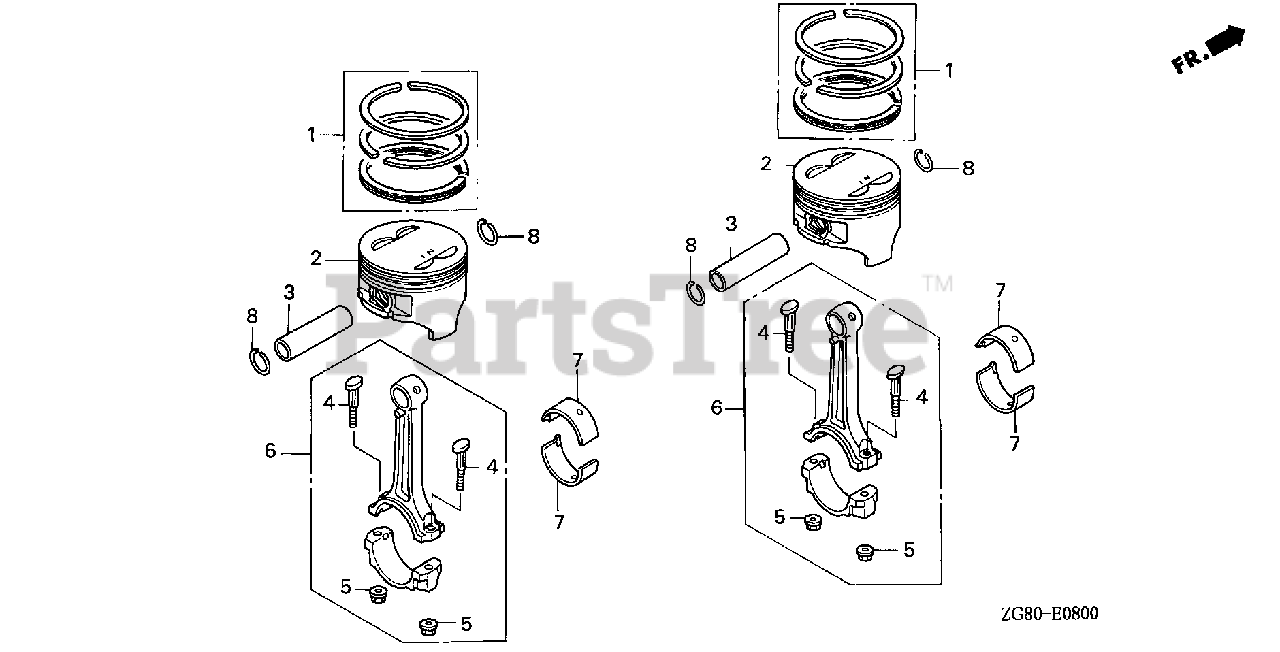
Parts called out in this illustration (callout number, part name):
1	RING SET, PISTON (STD) (RIKEN)
1	RING SET, PISTON (0.25) (RIKEN)
1	RING SET, PISTON (0.50) (RIKEN)
2	PISTON (STD)
2	PISTON (0.25)
2	PISTON (0.50)
3	PIN, PISTON
4	BOLT, CONNECTING ROD (TOKAI TRW)
5	NUT, CONNECTING ROD
6	ROD ASSY., CONNECTING
7	BEARING A, CONNECTING ROD (BLUE)
7	BEARING B, CONNECTING ROD (BLACK)
7	BEARING C, CONNECTING ROD (BROWN)
7	BEARING D, CONNECTING ROD (GREEN)
7	BEARING E, CONNECTING ROD (YELLOW)
7	BEARING F, CONNECTING ROD (PINK)
7	BEARING G, CONNECTING ROD (RED)
8	CLIP, PISTON PIN (19MM)
